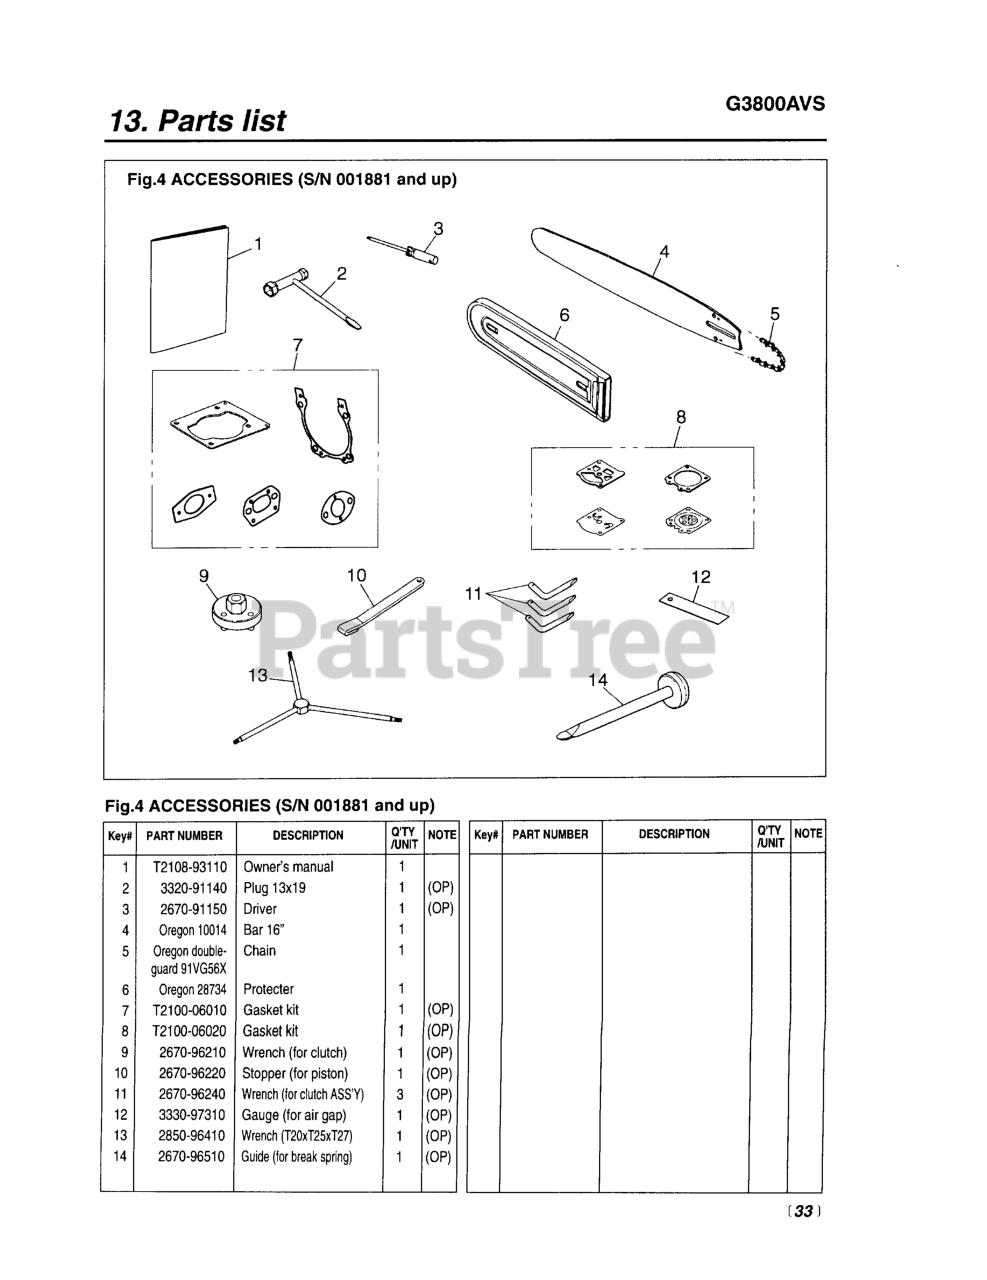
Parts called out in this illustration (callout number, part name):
2	WRENCH, PLUG
3	SCREWDRIVER
4	BAR 16
6	PROTECTOR (OREGON 28734)
7	KIT, GASKET (G3800AVS)
8	KIT, GASKET (G3800AVS)
9	WRENCH (TOOL)
10	STOPPER (TOOL)
11	WRENCH (TOOL)
12	GAUGE (TOOL)
13	WRENCH (RPLS. 2670-96410)
14	GUIDE (TOOL)
